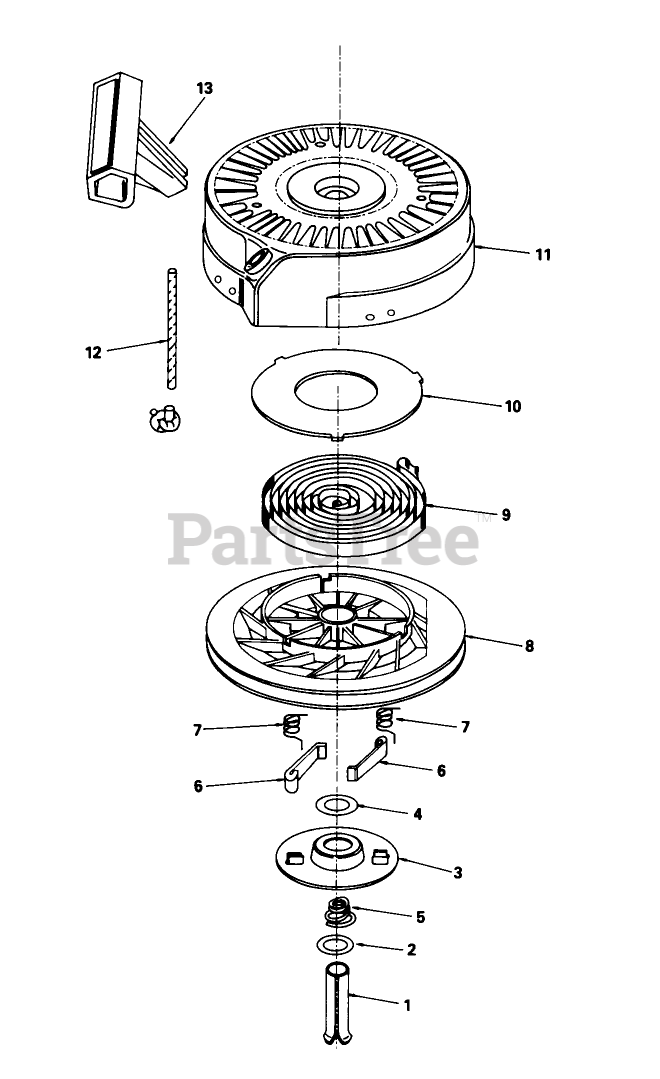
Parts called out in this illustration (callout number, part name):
1	Pin Spring
2	Washer
3	Retainer
4	Washer
5	Brake Spring
6	Dog-Starter
7	Spring-Dog
8	Pulley
9	Rewind Spring
10	Cover-Spring
11	Housing-Starter
12	Rope-Starter (98 cut to length)
13	Handle-Starter
